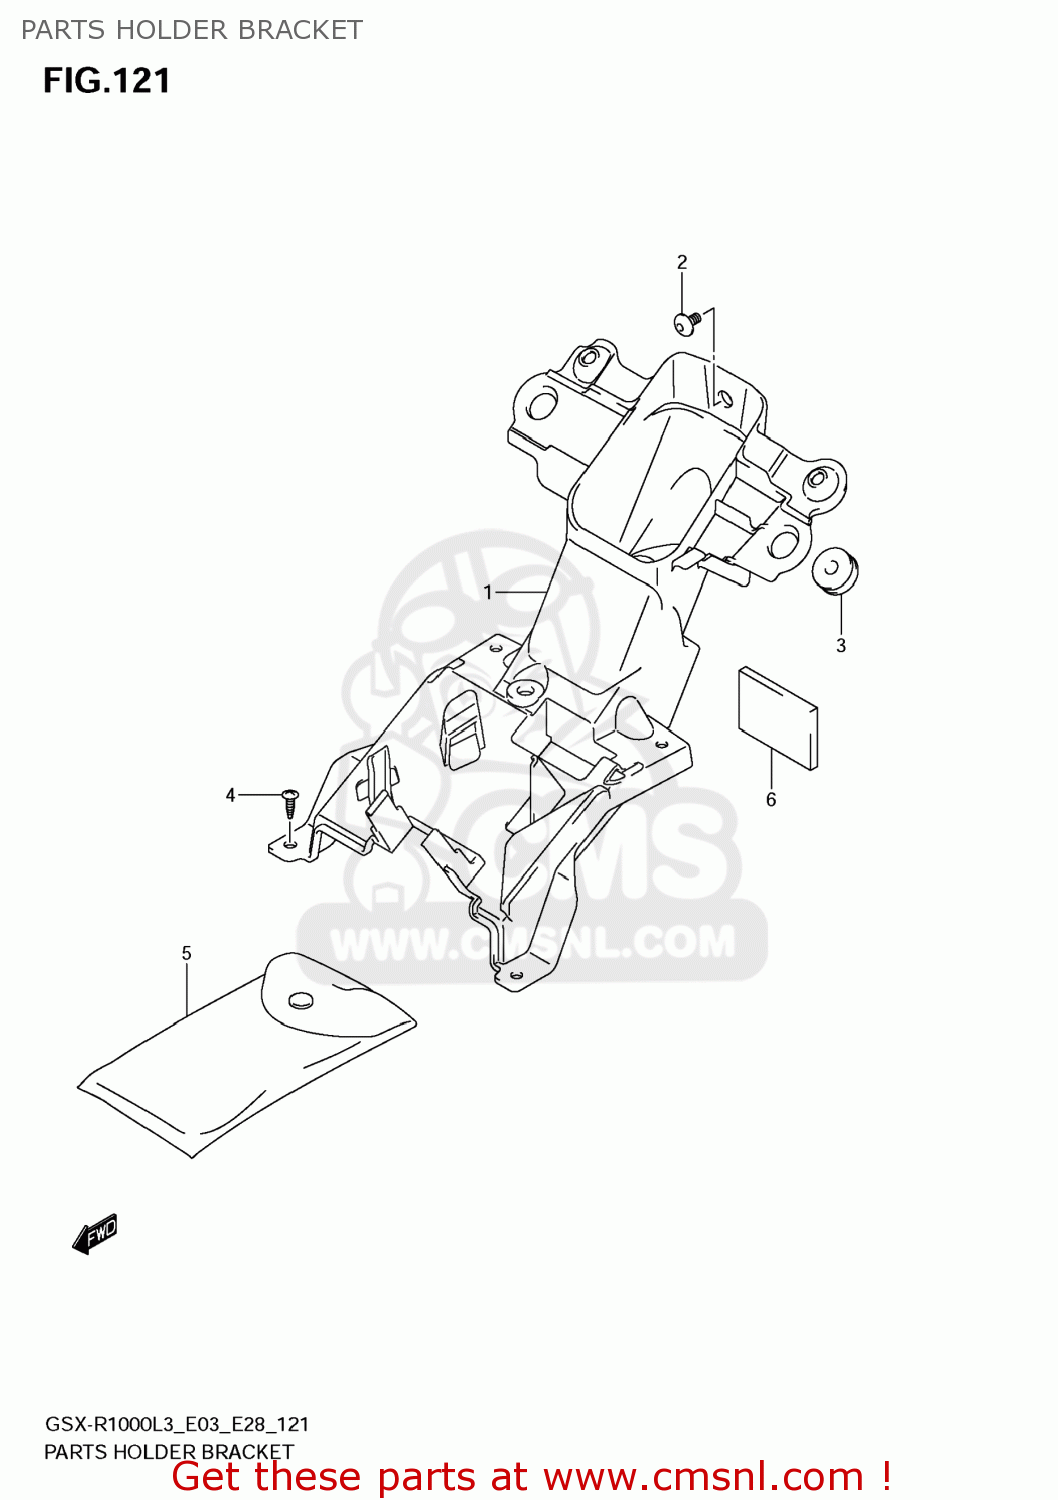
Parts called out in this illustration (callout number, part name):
1	BRACKET,ELECTRIC PARTS HOLDER
2	SCREW(6X12)
3	CUSHION
4	SCREW
5	TOOL ASSY
6	PROTECTOR(50X50X5)
